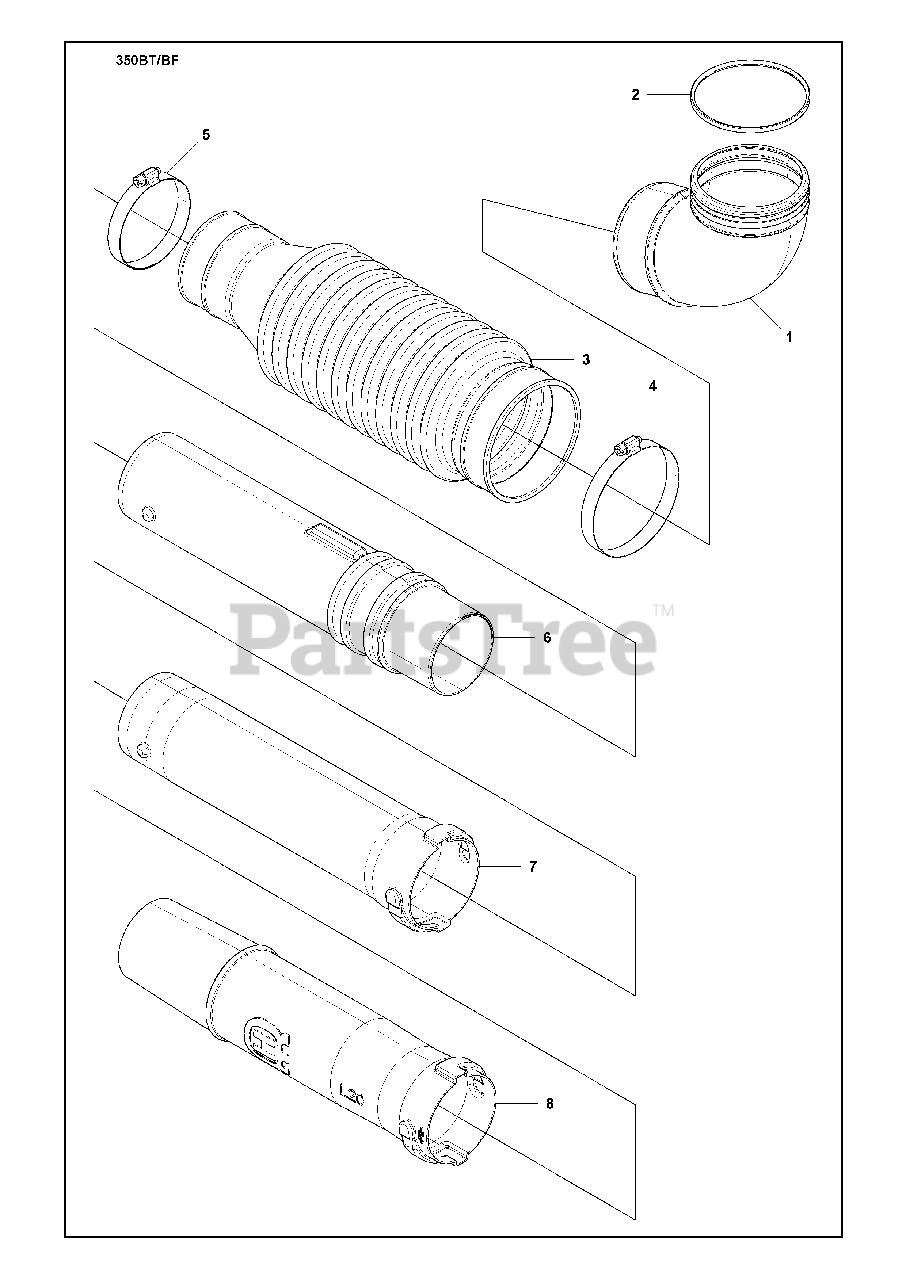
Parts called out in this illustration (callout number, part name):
1	PIPE BEND
2	O-RING
3	BELLOWS
4	CLAMP(F115)
6	SWIVEL JOINT
7	PIPE STRAIGHT
